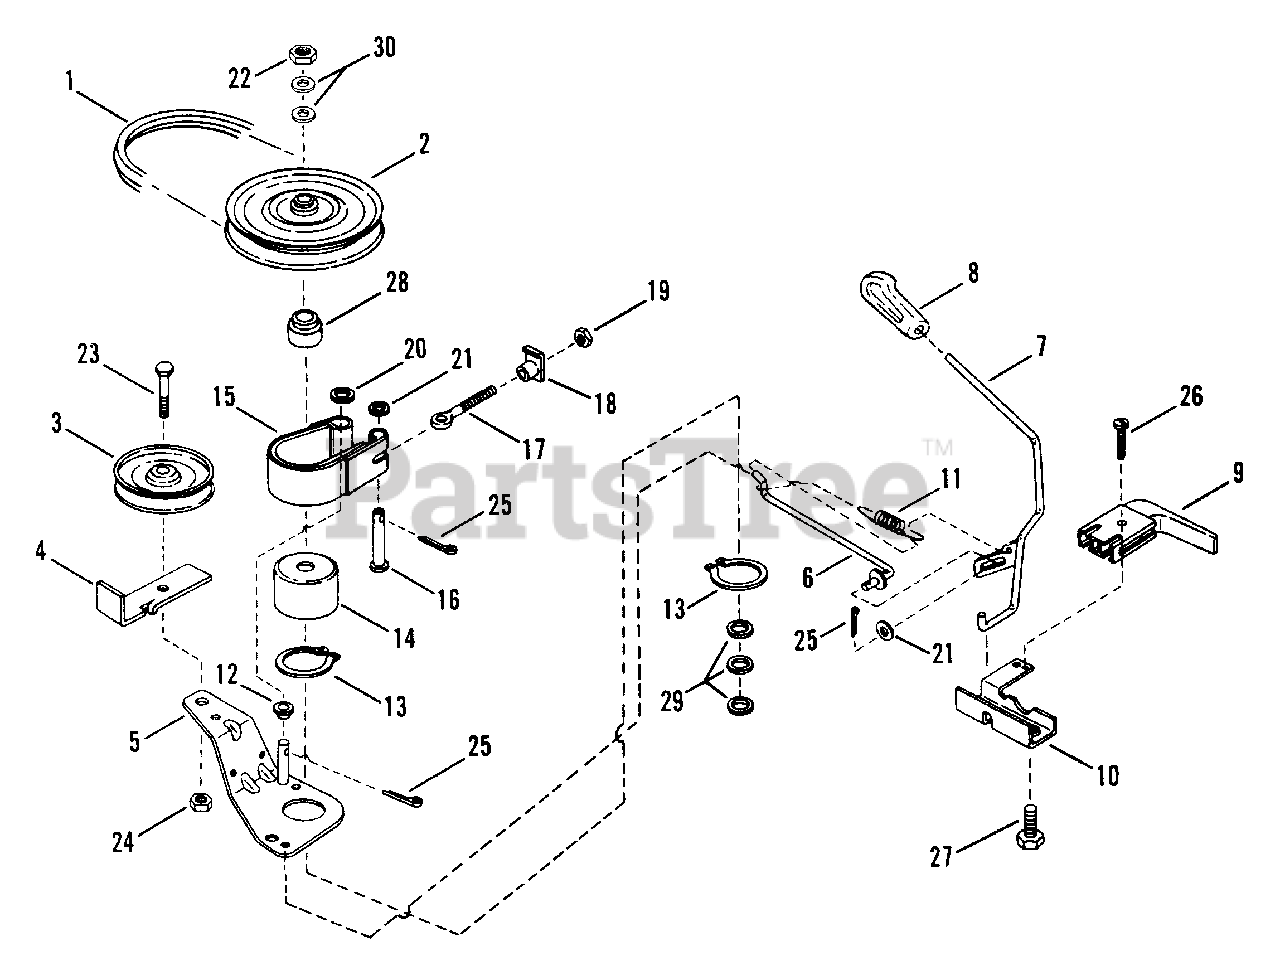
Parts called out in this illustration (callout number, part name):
1	BELT, Drive
2	PULLEY, Spindle
3	PULLEY, Idler
4	RESTRICTOR, Belt
5	ARM, Idler
6	ROD, Idler
7	HANDLE, Blade ON - OFF (Lever)
8	GRIP, Handle
9	SWITCH, Deck Interlock
10	MOUNT, Handle
11	SPRING, Blade Handle
12	SPACER
13	RING, 2" External Retaining
14	DRUM, Brake
15	BAND, Brake Assembly
16	PIN, 1/4 x 1-5/8" Clevis
17	BOLT, 1/4 - 20 Eye
18	NUT, 1/4 - 20 Tee
19	NUT, 1/4 - 20 Hex
20	WASHER, 3/8" Flat
21	WASHER, 1/4 Flat
22	NUT, 3/4-16 Hex Jam
23	SCREW, 3/8 - 24 x 1-3/4" Hex Head Cap
24	NUT, 3/8 - 24 Hex Lock
25	PIN, 3/32 x 3/4" Cotter
26	SCREW, #10 - 32 x 1" Self-Tapping
27	SCREW, 1/4 - 20 x 5/8" Self-Tapping
28	HUB, Pulley
29	WASHER, 49/64 x 1-1/8" Flat
30	WASHER, 49/64 x 1-1/2" Flat
